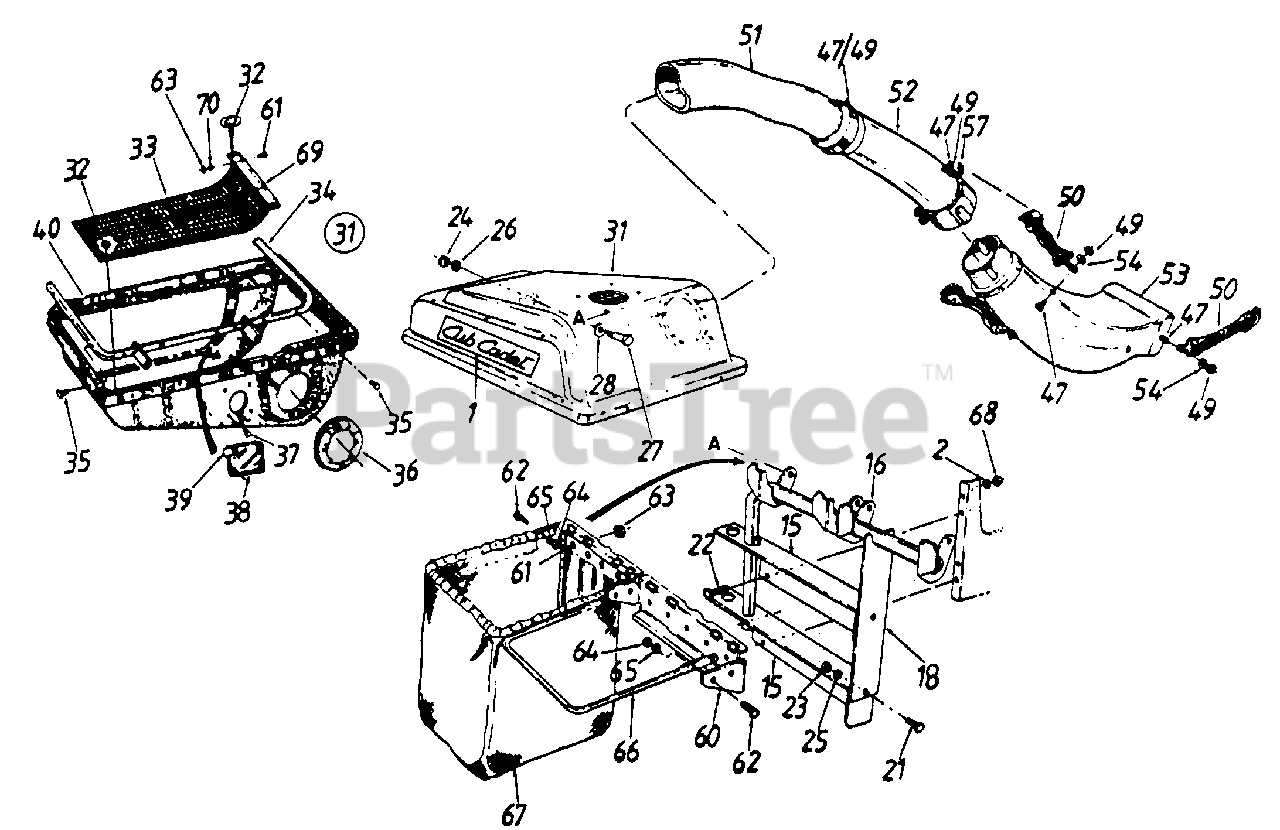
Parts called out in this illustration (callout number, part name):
1	PLATE-NAME-CUB CADET-BAGGER
2	WASHER-FL-.266X.625
15	BRACKET-MTG
16	TUBE ASSY-SUPPORT
18	BRACKET-SUPPORT
21	SCREW-HEX 5/16-18 X .75
22	SCREW-1/4-20 X .62
23	NUT-HEX 5/16-18
24	NUT-HEX 3/8-16
25	WASHER-LOCK-5/16
26	WASHER-LOCK-3/8
27	SCREW-SHLD
28	WASHER-BELL .505 ID X 1.00 OD
31	COVER ASSY-GRASS
32	FASTENER-TWIST
33	SCREEN ASSY
35	SCREW-HEX TAP
36	SEAL
37	SCREW-TRUSS MACH
38	PLATE-PLASTIC
39	NUT-SPEED
40	COVER ASSY-GRASS
47	SCREW-HEX 1/4-20 X .50
49	NUT-INS LOCK 1/4-20
50	STRAP ASSY-RETAINER
51	ELBOW-CATCHER
52	TUBE-CATCHER
53	DISCHARGE CHUTE - W/CUTOUT
54	WASHER-SPRING.270 ID X.51 OD X.030
57	BRACKET-HOOK RETAIN
61	SCREW-TRUSS MACH #10-24 X .50
62	SCREW-HEX 1/4-28 X .75
63	NUT-SEMS 10-24
64	NUT-HEX 1/4-28
65	LOCK WASHER 1/4 DIA
67	BAG-GRASS
68	NUT-HEX 1/4-20 GR 5
69	SCREEN ASSY
70	WASHER-FL .192 X .625 X .057
